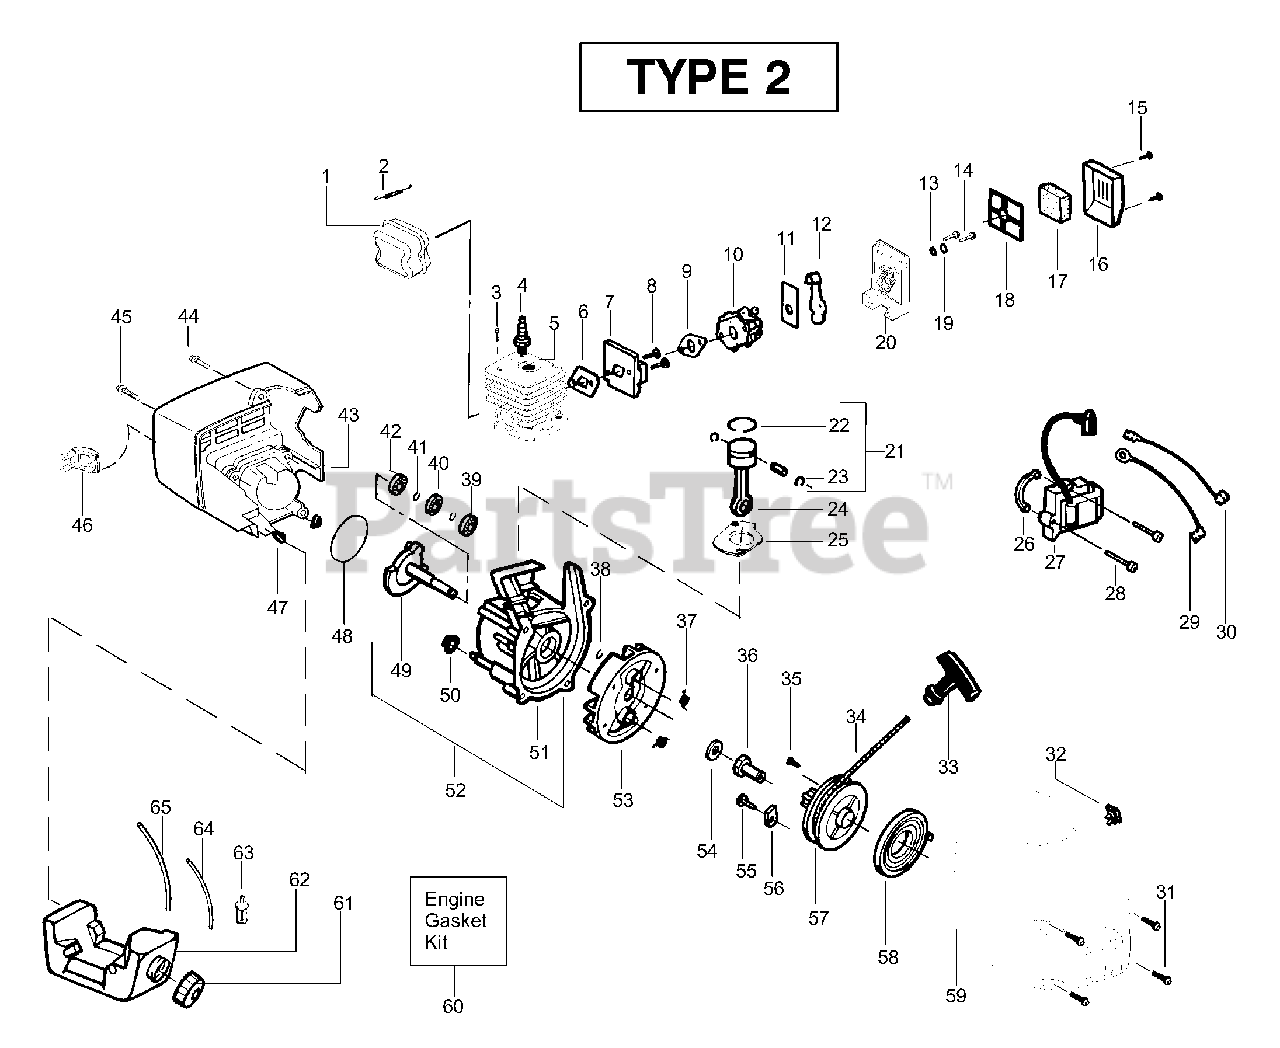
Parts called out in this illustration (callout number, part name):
1	Kit - Muffler
2	Muffler Spring
3	Screw-Cylinder
4	Spark Plug (RCJ-6Y)
5	Kit - Cylinder
6	Gasket-Cyl/Carb. (kit)
7	Adaptor-carb.
9	Gasket-Carb. (kit)
10	Kit-Carb. (WA226)
11	Plate-Choke Mounting
12	Lever-Choke
16	Cover-Air Box
17	Foam-Air Filter
18	Plate-Air Filter Support
19	Spacer-Choke
21	Kit - Piston
22	Piston Ring
23	Retainer-Piston Pin
24	Assy-Connecting Rod
25	Gasket-Cylinder (kit)
26	Spacer-Module
27	Ignition Module
29	Assy-Ground Wire
30	Assy-Leadwire
31	Screw
32	Kit-Switch
33	Handle-Starter
34	Kit - Rope
36	Coupling-Drive
37	Spring-Starter Dog
38	Retain. Ring-C'shaft
39	Bearing-Outer
40	Seal-C'case
41	Retainer Ring-C'case
42	Bearing-Inner
45	Screw
46	Guard-Muffler
47	Isolator-Shroud
48	O-Ring-C'case (kit)
49	Assy-Crankshaft
50	Isolator-Crankcase
51	Assy-Crankcase
52	Assy-C'case & C'shaft
53	Assy-Flywheel
54	Washer-Flat
56	Retainer-Can
57	Kit-Starter Pulley
58	Spring-Starter
59	Assy-Fan Housing
60	Kit-Engine Gasket
61	Assy-Fuel Cap
62	Assy-Fuel Tank
63	Assy-Fuel Pickup
64	Kit-Fuel Line
65	Kit-Fuel Line
